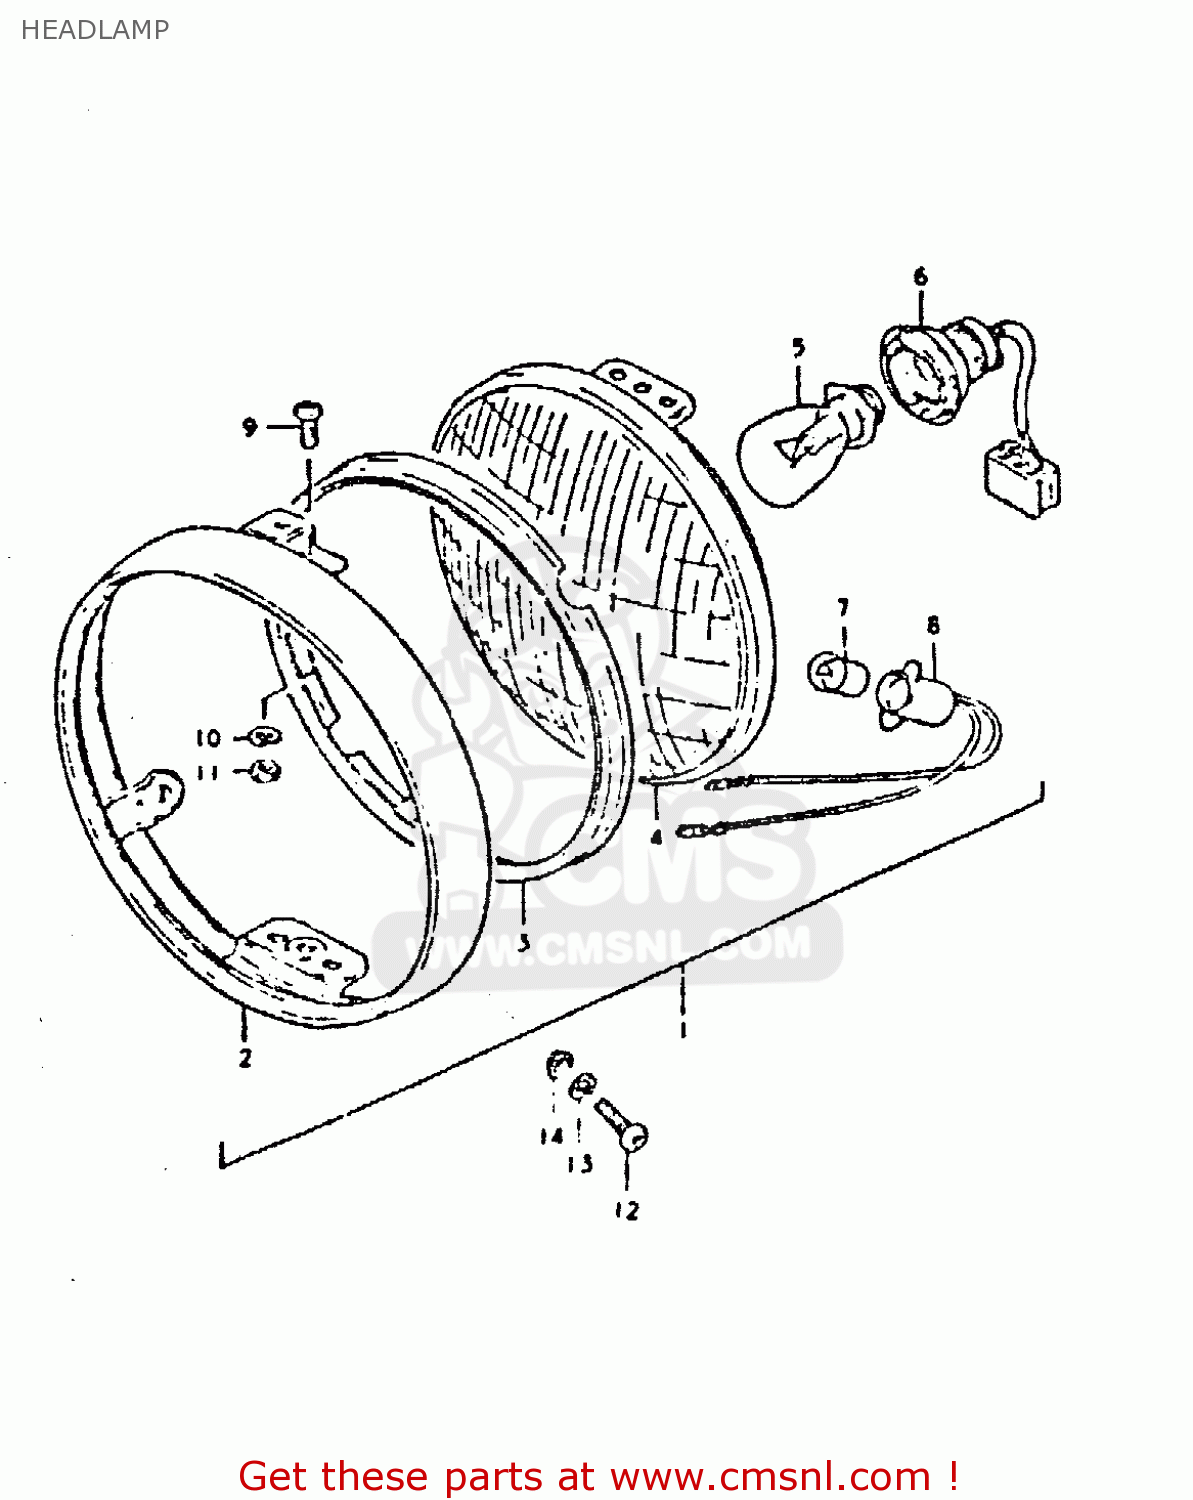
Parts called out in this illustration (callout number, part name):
1	HEADLAMP ASSY
2	RIM
3	RETAINER,HEADLAMP
4	UNIT, HEAD LIGHT
5	BULB 12V35/35W
6	SOCKET
7	BULB(12V3.4W,STANLEY,A72A)
8	SOCKET
9	SCREW
10	LOCK WASHER
11	NUT
12	SCREW
13	WASHER,LOCK
14	WASHER
